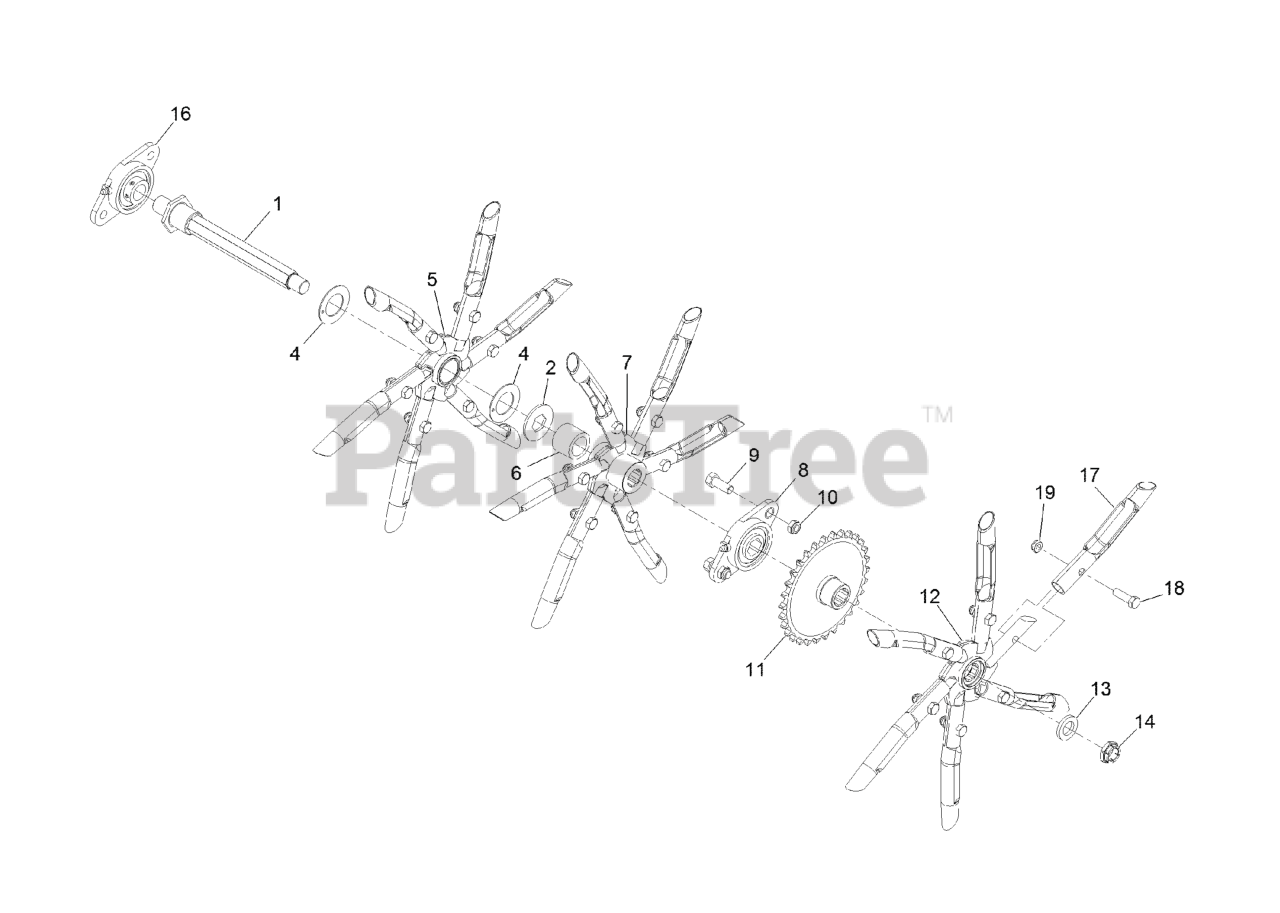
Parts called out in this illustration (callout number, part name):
1	TINE SHAFT ASM
2	KEEPER-TINE, FLOATING
4	WASHER-THRUST
5	FLOATING SPYDER ASM
6	SPACER-TINE
7	DRIVEN SPYDER ASM
8	BEARING-HEX BORE
9	SCREW-HH
10	NUT-LOCK
11	SPROCKET ASM
12	DRIVEN SPYDER ASM
13	WASHER-SPACER
14	NUT-LOCK
16	BEARING-ROUND BORE
17	TINE-CORING (3/4 INCH)
18	SCREW-HH
